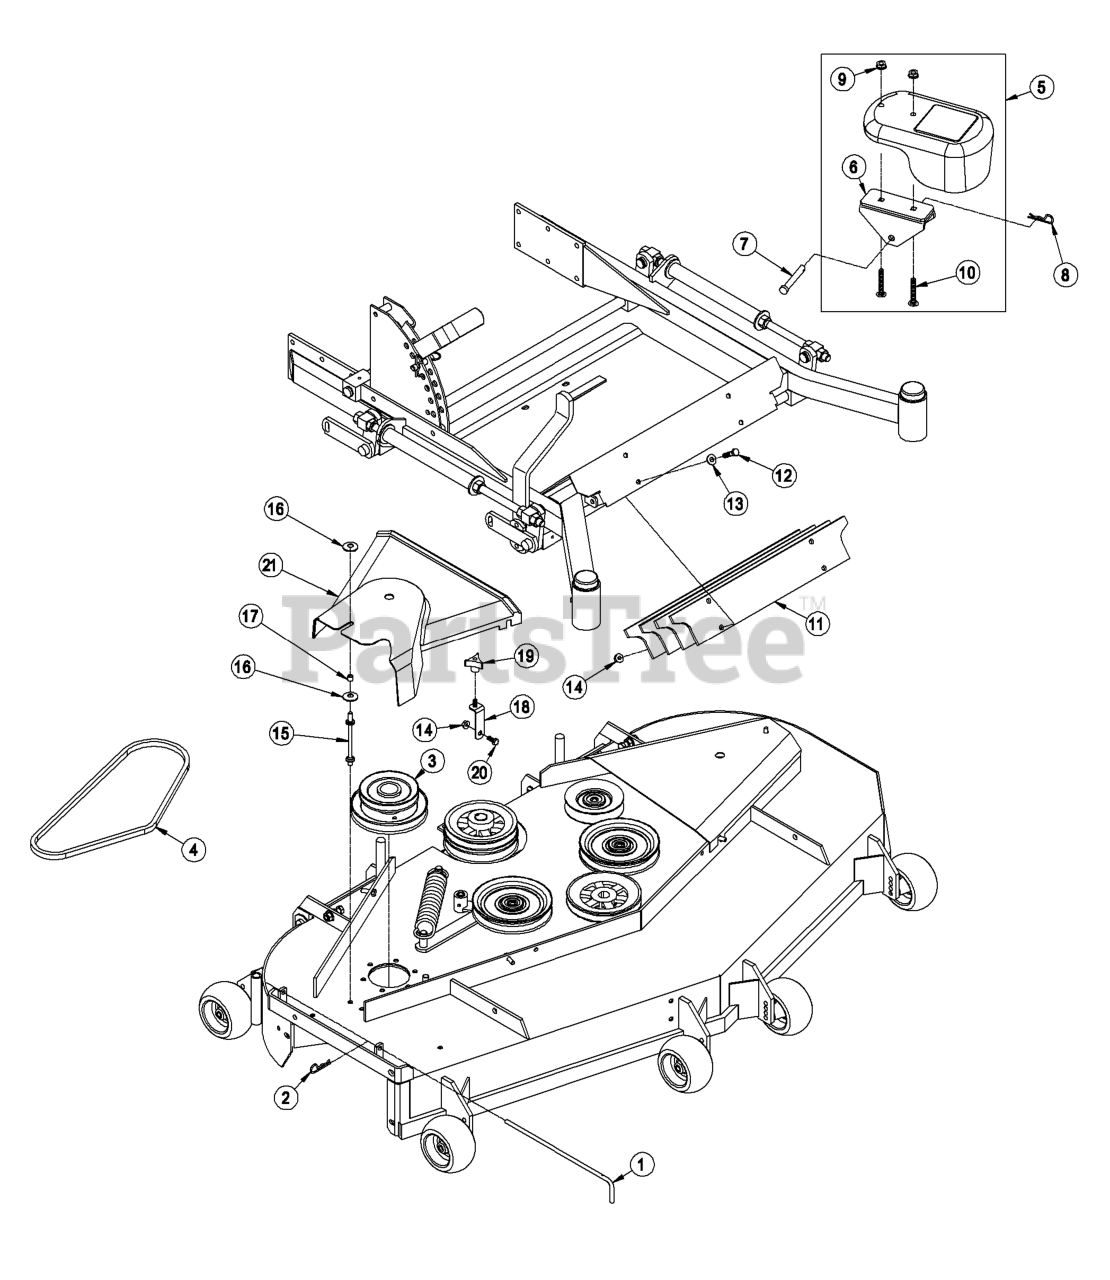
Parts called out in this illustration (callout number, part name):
1	PIN, CHUTE PIVOT
2	PIN-COTTER
4	BELT, BLOWER DRIVE 72
5	ASM, WEIGHT 2.0" 43 POUND
7	PIN-CLEVIS
8	PIN-COTTER
9	NUT-HHF, WHIZ
10	SCREW-CARR
12	SCREW-HH
13	WASHER-PLAIN
15	STUD,BELT SHIELD 4 INCH
16	WASHER-SPRING
17	SPACER
18	WLD, BELT COVER SUPPORT
19	KNOB-3 PRONG
20	BOLT-CARR
21	COVER, BELT 72
